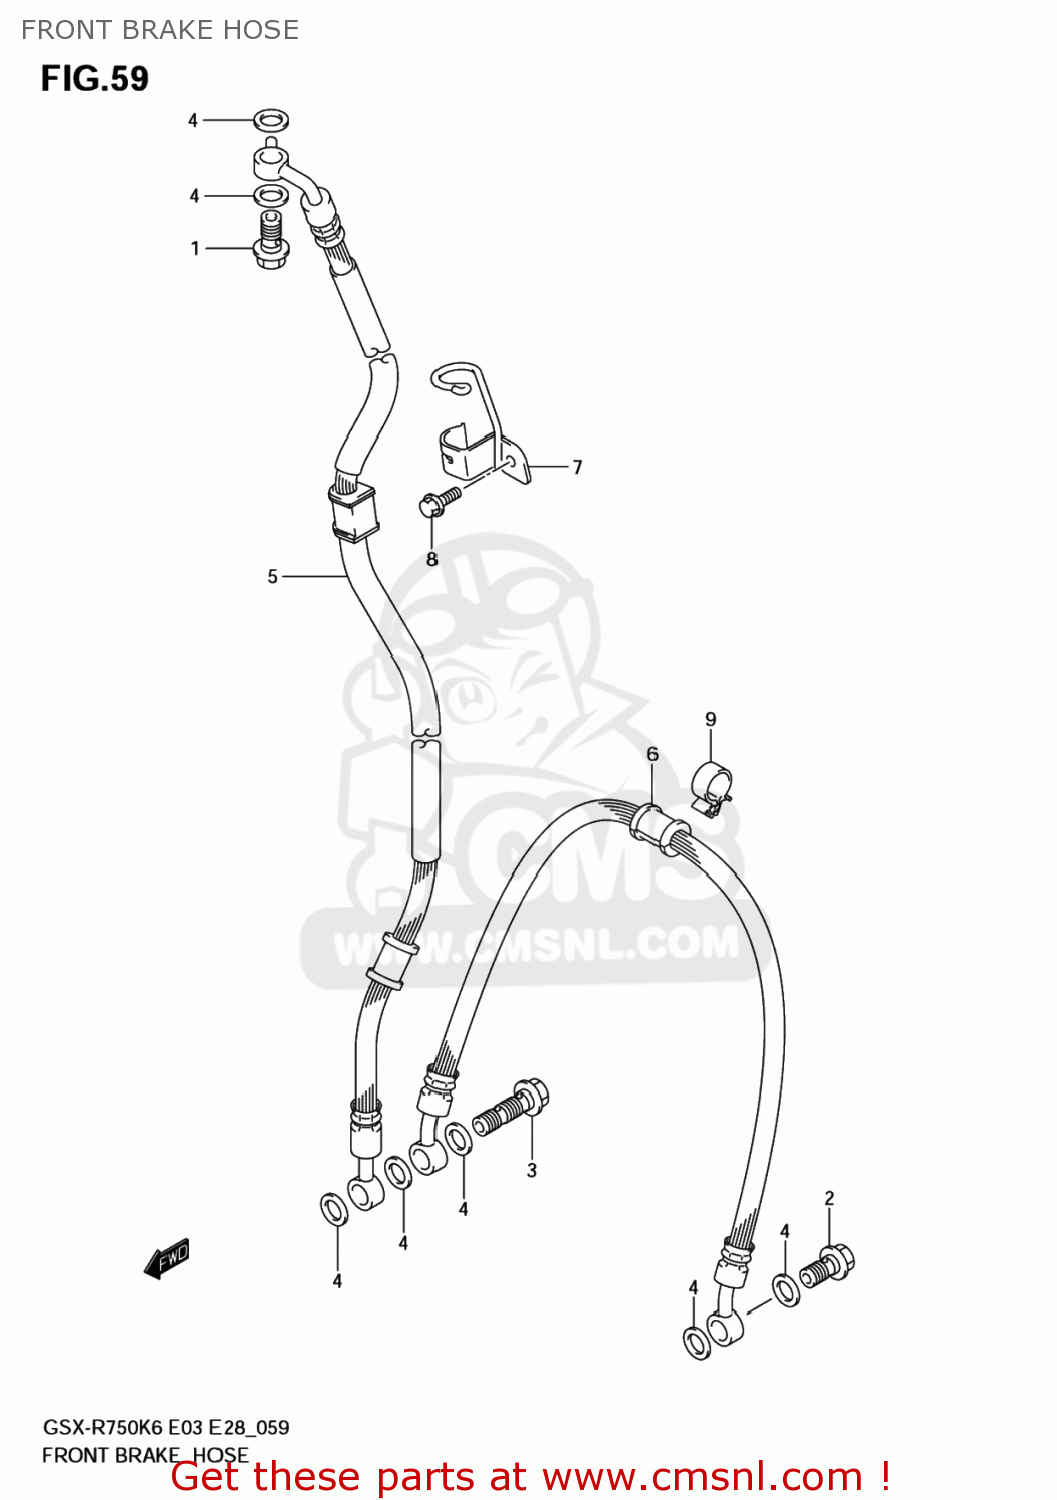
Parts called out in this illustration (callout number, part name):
1	BOLT (10X22)
2	BOLT (10X22)
3	BOLT (10X36)
4	WASHER(10X15X1.5)
5	HOSE,FR BRAKE NO.1
6	HOSE,FR BRAKE NO.2
7	CLAMP, BRAKE HOSE NO.1
8	BOLT
9	CLAMP
